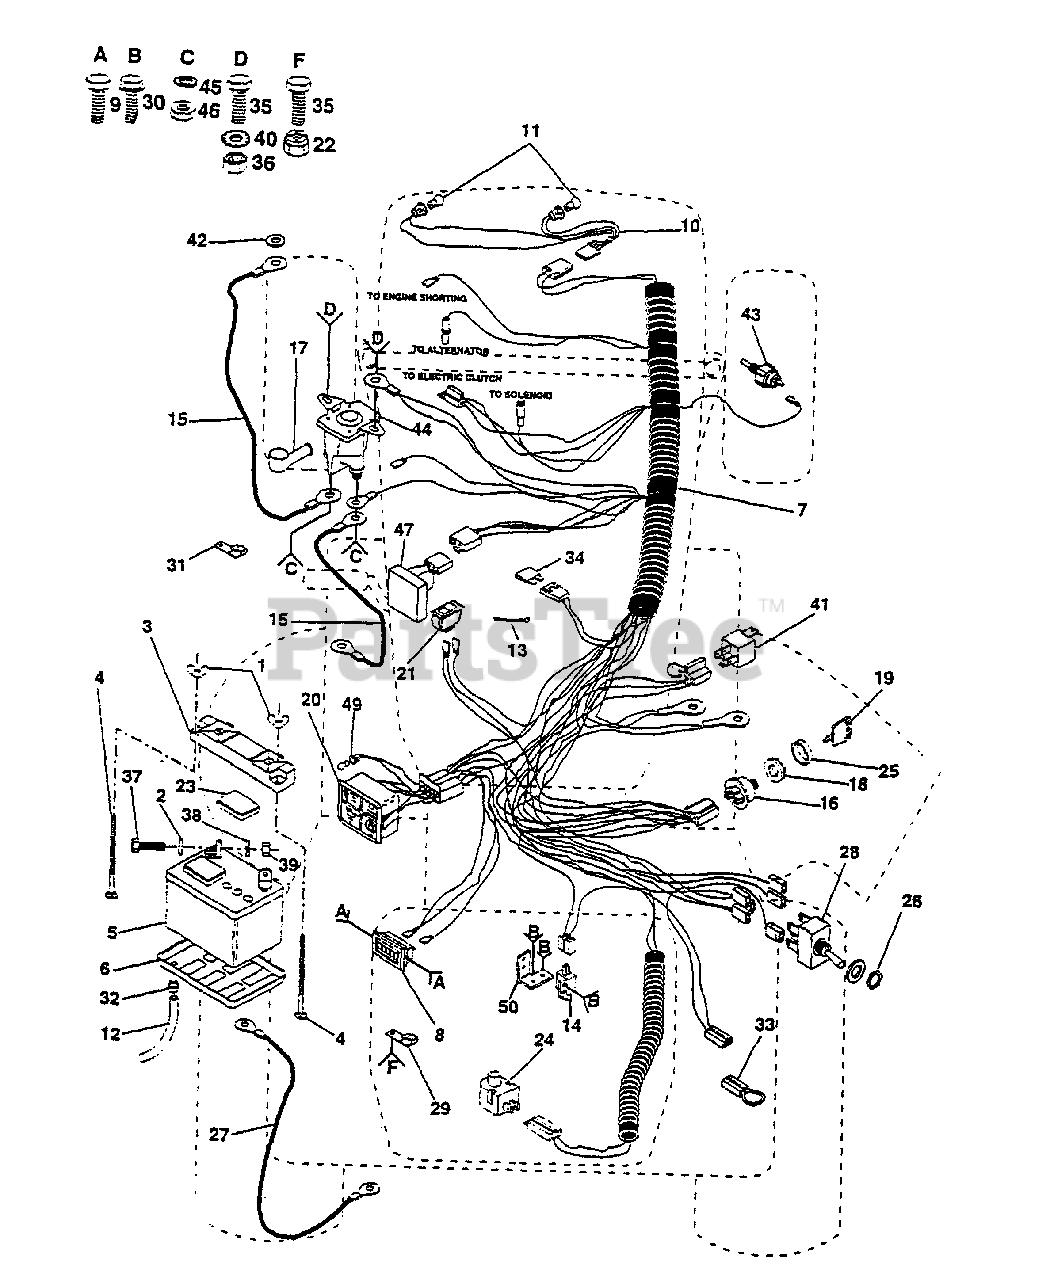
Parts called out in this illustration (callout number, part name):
1	Nut, Wing 1/4-20
2	Washer 9/32 x 5/8 x 16 Gauge
3	Guard, Terminal
4	Bolt, Carriage 1/4-20 x 7-1/2
5	Battery
6	Tray, Battery
7	Harness, Ignition
8	Meter, Hour
9	Screw #10-24 x 1/2
10	Harness, Socket, Light
11	Bulb, Light
12	Tube, Tray, Battery
13	Cable Tie
14	Switch, Clutch, Interlock
15	Cable, Battery
16	Switch, Ignition
17	Cover, Terminal
18	Nut, Ignition
19	Key, Molded
20	Package, Light
21	Switch, Light
22	Nut, Crownlock 1/4-20
23	Caps, Battery
24	Switch, Plunger
25	Bezel, Ignition
26	Nut, Hex
27	Cable, Battery
28	Switch, P.T.O.
29	Clip, Insulated
30	Screw, Hex Tap #10-24 UNC
31	Clip, Fuel Line
32	Clamp, Hose
33	Loop, Wire
35	Bolt, Hex 1/4-20 x 1/2 Grade 5
36	Nut, Hex, Keps 1/4-20
37	Bolt, Hex Head 1/4-20 x 3/4
38	Washer, Lock 1/4
39	Nut, Hex 1/4-20
40	Washer, Lock, External Tooth 1/4
42	Washer, Lock, Internal Tooth 1/4
43	Switch, Oil Sensor
44	Solenoid
45	Washer, Lock 1/4
46	Nut, Hex, Jam 1/4-20
47	Sensor, Low Voltage
48	Washer 17/32 x 3/4 x 16 Ga.
49	Bulb, Light Package
50	Bracket Switch Interlock
